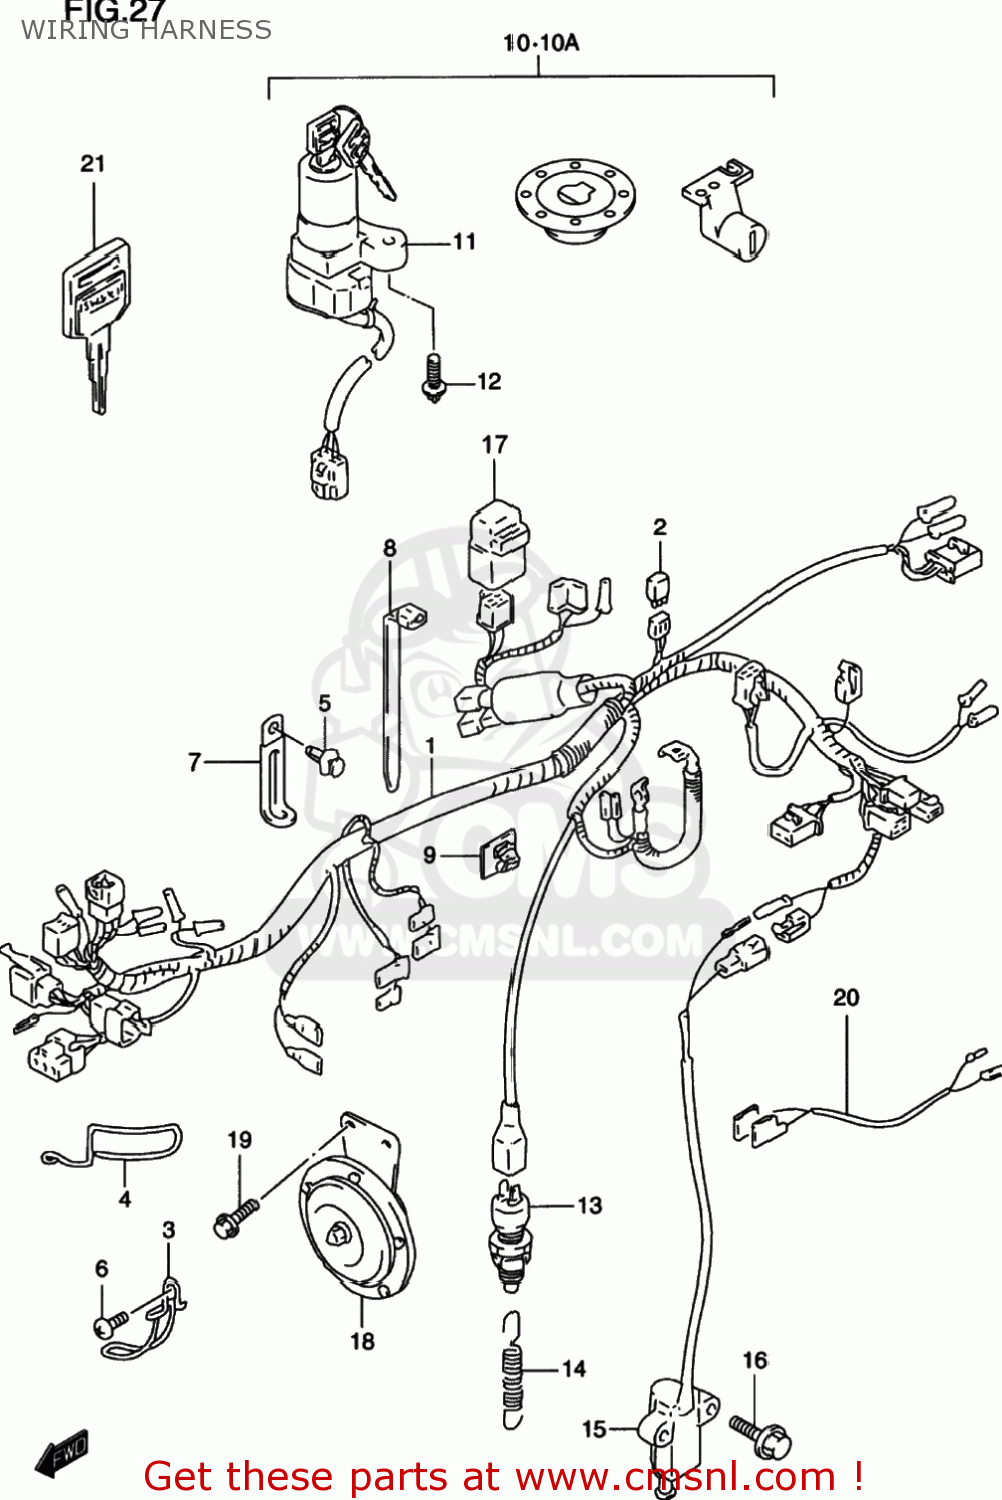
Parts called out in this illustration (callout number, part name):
1	HARNESS,WIRING
2	DIODE(STANLEY DE8804)
3	PROTECTOR
4	PROTECTOR
5	CLIP(BLACK)
6	SCREW 6X12
7	CLAMP(L:65)
8	CLAMP L:165
9	CLAMP
10	LOCK SET
10A	LOCK SET
11	LOCK ASSEMBLY,STEERING
12	SCREW(6X18)
13	SWITCH ASSY,STOP LAMP
14	SPRING
15	SWITCH ASSY,SIDE STAND
16	BOLT
17	RELAY ASSY
18	HORN ASSY
19	BOLT
20	WIRE,CLUTCH LEAD
21	KEY,BLANK
